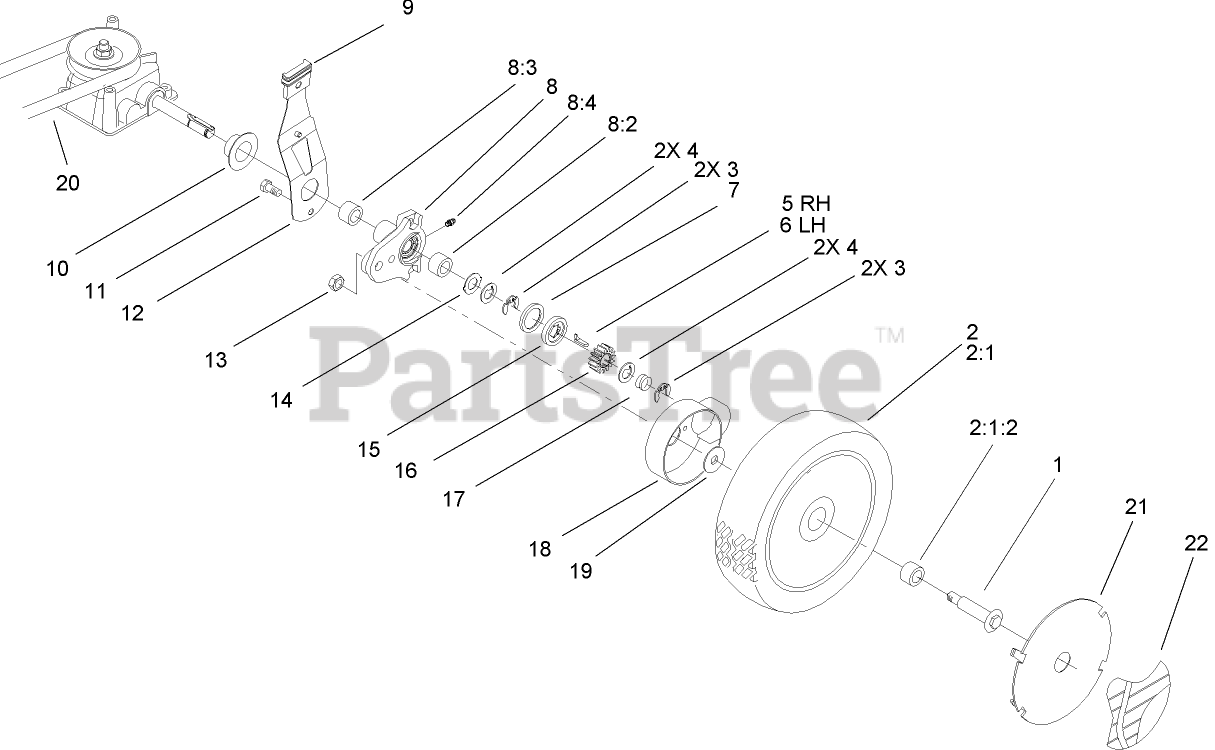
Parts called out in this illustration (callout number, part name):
1	BOLT-SHOULDER
2	WHEEL ASM
2:1	Wheel ASM
2:1:2	BUSHING
3	RING-RETAINING,CLIP
4	WASHER-THRUST, KEYED
5	KEY-ROCKING, RH
6	KEY-ROCKING, LH
7	RING-FRICTION
8	PIVOT ARM ASM
8:2	BUSHING
8:3	BUSHING
8:4	FITTING-GREASE
9	KNOB-ARM
10	CAP-END
11	SCREW-HWH
12	SPRING ARM ASM
13	LOCKNUT
14	WASHER-ARM, PIVOT
15	WASHER-CLUTCH
16	GEAR-PINION
17	SPRING-COMPRESSION
18	COVER-WHEEL
19	SPACER-COVER, WHEEL
20	BELT-V
21	COVER-WHEEL
22	LABEL-WHEEL, SMART
